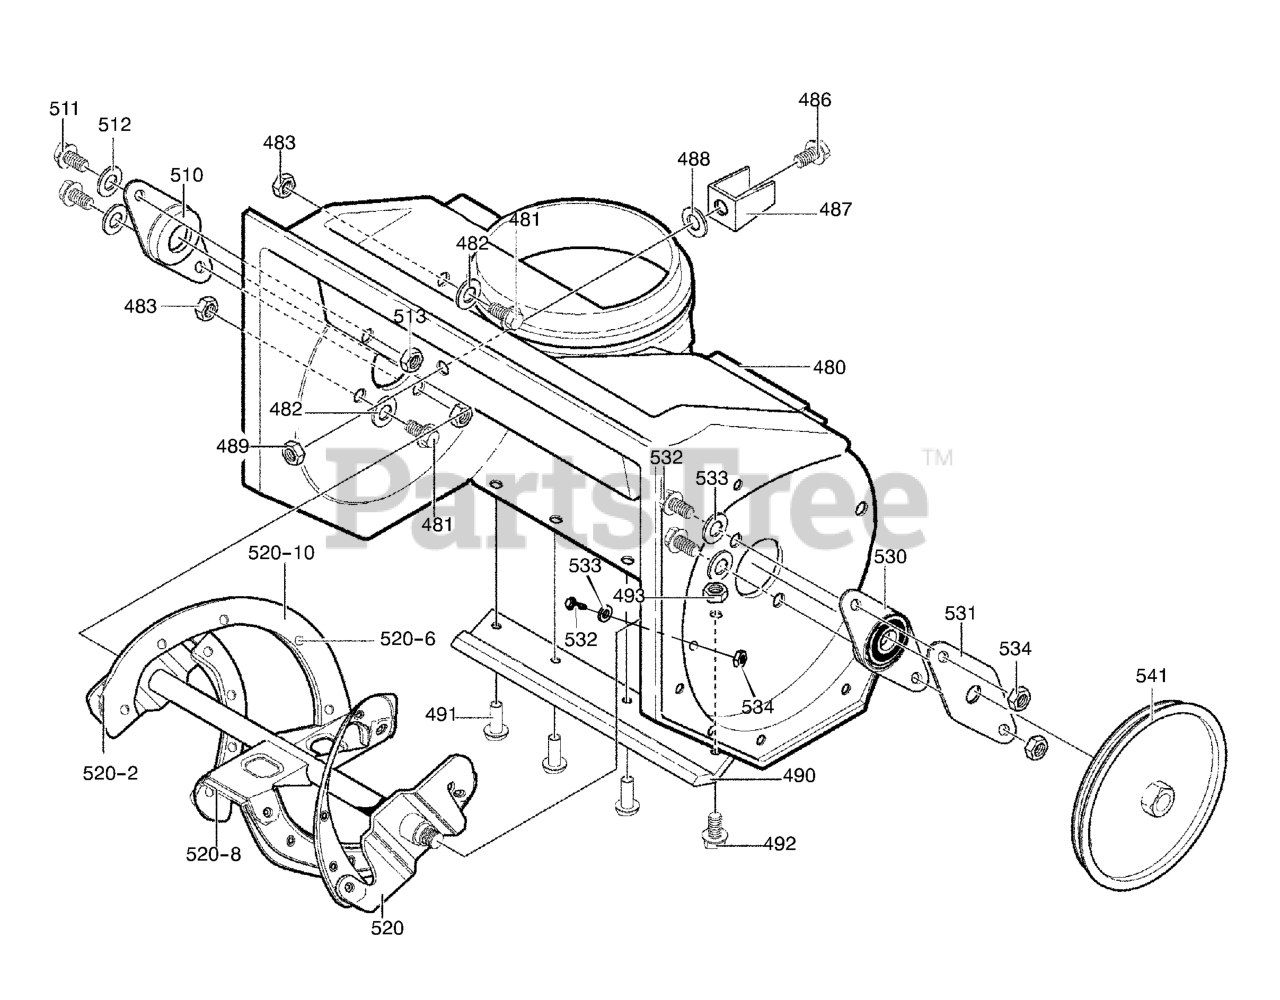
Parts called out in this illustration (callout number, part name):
480	HOUSING, ASSY
481	SCREW, 1/4-20X.75
482	WASHER, FLAT .281X.63X.065
483	NUT, 1/4-20 REGHEXCTRLK
486	SCREW, 1/4-20X.63
487	BRACKET, STOP
488	WASHER, FLAT .333X.87X.119
489	NUT, 1/4-20 HEX NYLOCK
490	BLADE, SCRAPER
491	RIVET, OVSET .250DIAX.61LG
492	SCREW, 1/4-20X.75
493	NUT, CNTRLK 1/4-20
510	BEARING, FLANGE
511	SCREW, 1/4-20X1.00
512	WASHER, FLAT .281X.63X.065
513	NUT, CNTRLK 1/4-20
520	AUGER, ASSY
520-2	BLADE, AUGER
520-6	RIVET
520-8	BLADE, CENTER
520-10	AUGER & BLADE SUPPORT
530	BEARING & PLATE ASSY
531	PLATE, RETAINER
532	SCREW, 1/4-20X.63
533	WASHER, FLAT .281X.63X.065
534	NUT, 1/4-20 REGHEXCTRLK
541	PULLEY V3L 6.00 O.D.
